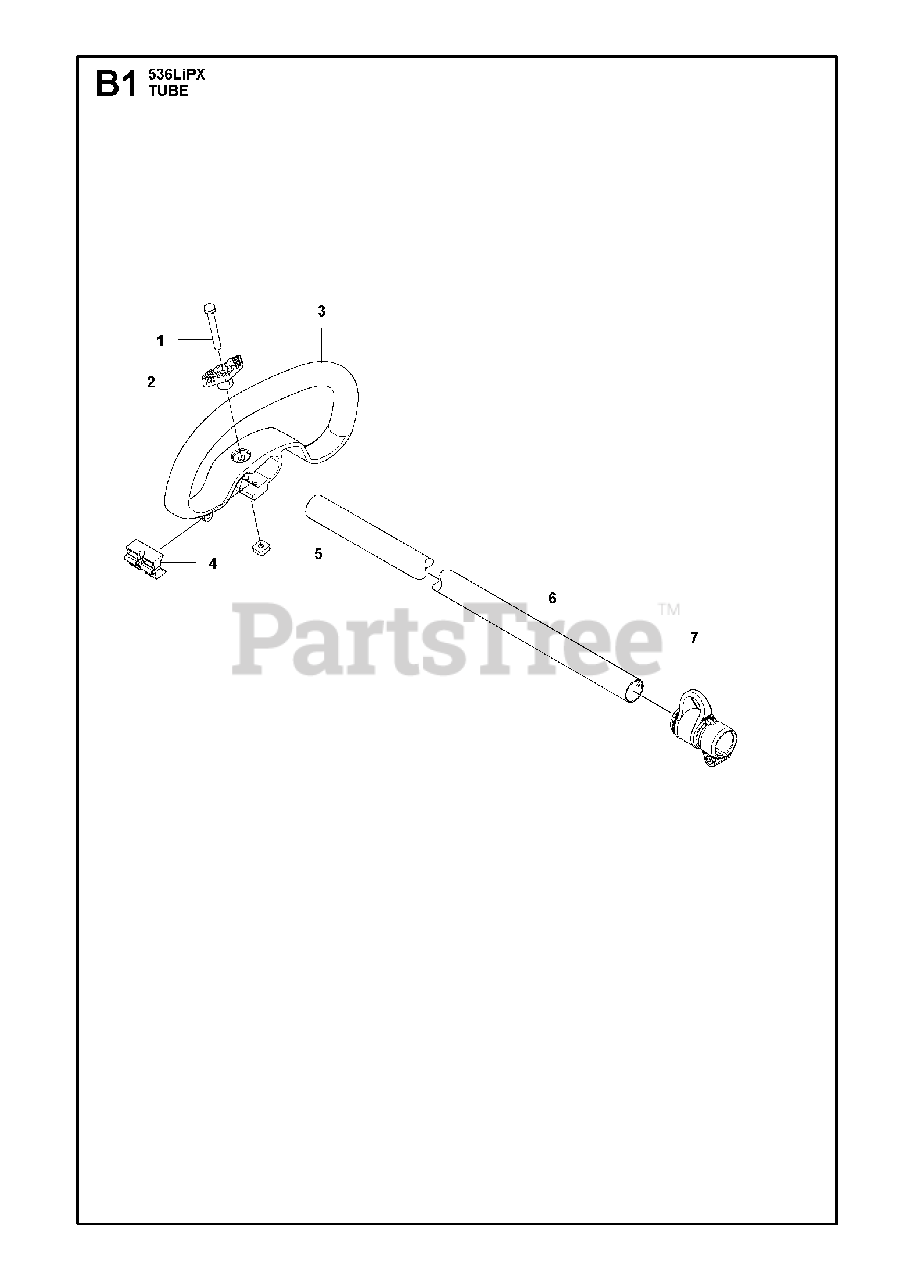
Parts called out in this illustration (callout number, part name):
1	SCREW M6X50
4	SPACER PLASTIC
7	CORD BRACKET CPL BATTERY POLE
